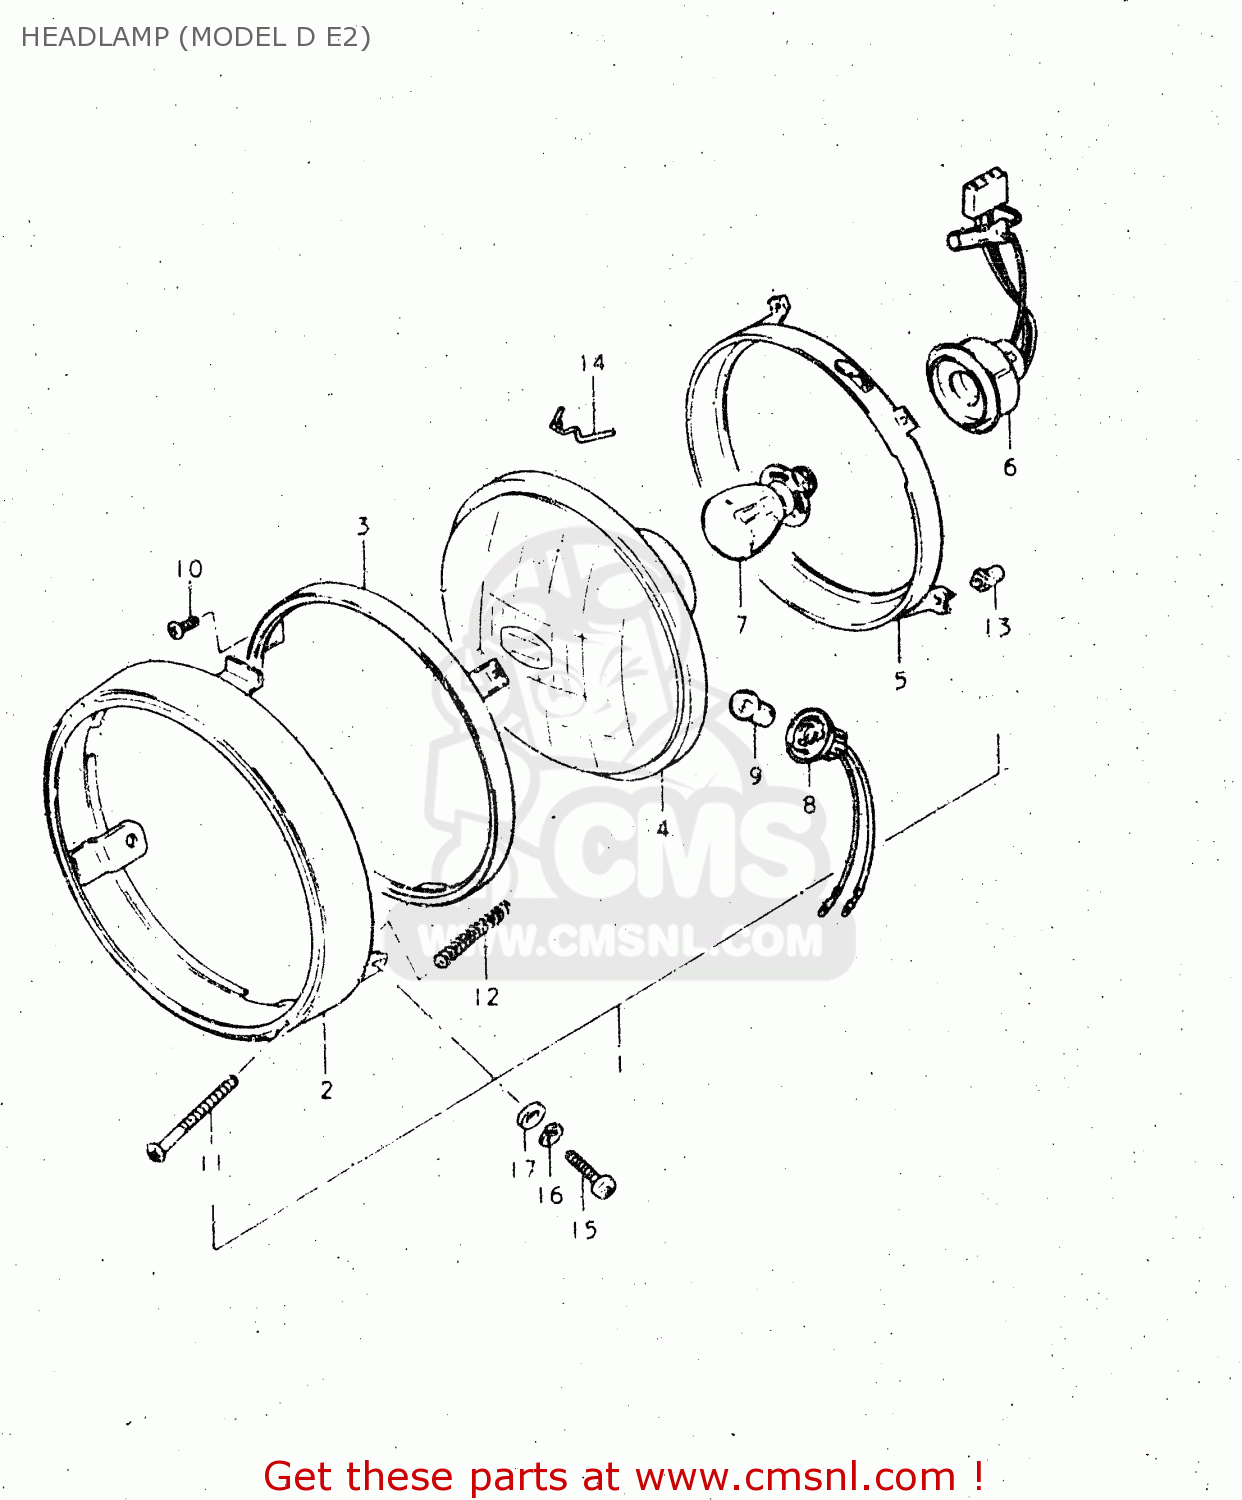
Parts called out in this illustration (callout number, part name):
1	HEADLAMP ASSY
2	RIM
3	RETAINER,HEADLAMP
4	UNIT
5	RING, MOUNTING
6	SOCKET
7	BULB(6V,35/35W)
8	SOCKET
9	BULB(6V/3W)
10	SCREW
11	SCREW,HEADLAMP ADJUST
12	SPRING,ADJUSTING
13	NUT,HEADLAMP ADJUSTER
14	SPRING,HEADLAMP UNIT
15	SCREW
16	LOCK WASHER
17	WASHER
